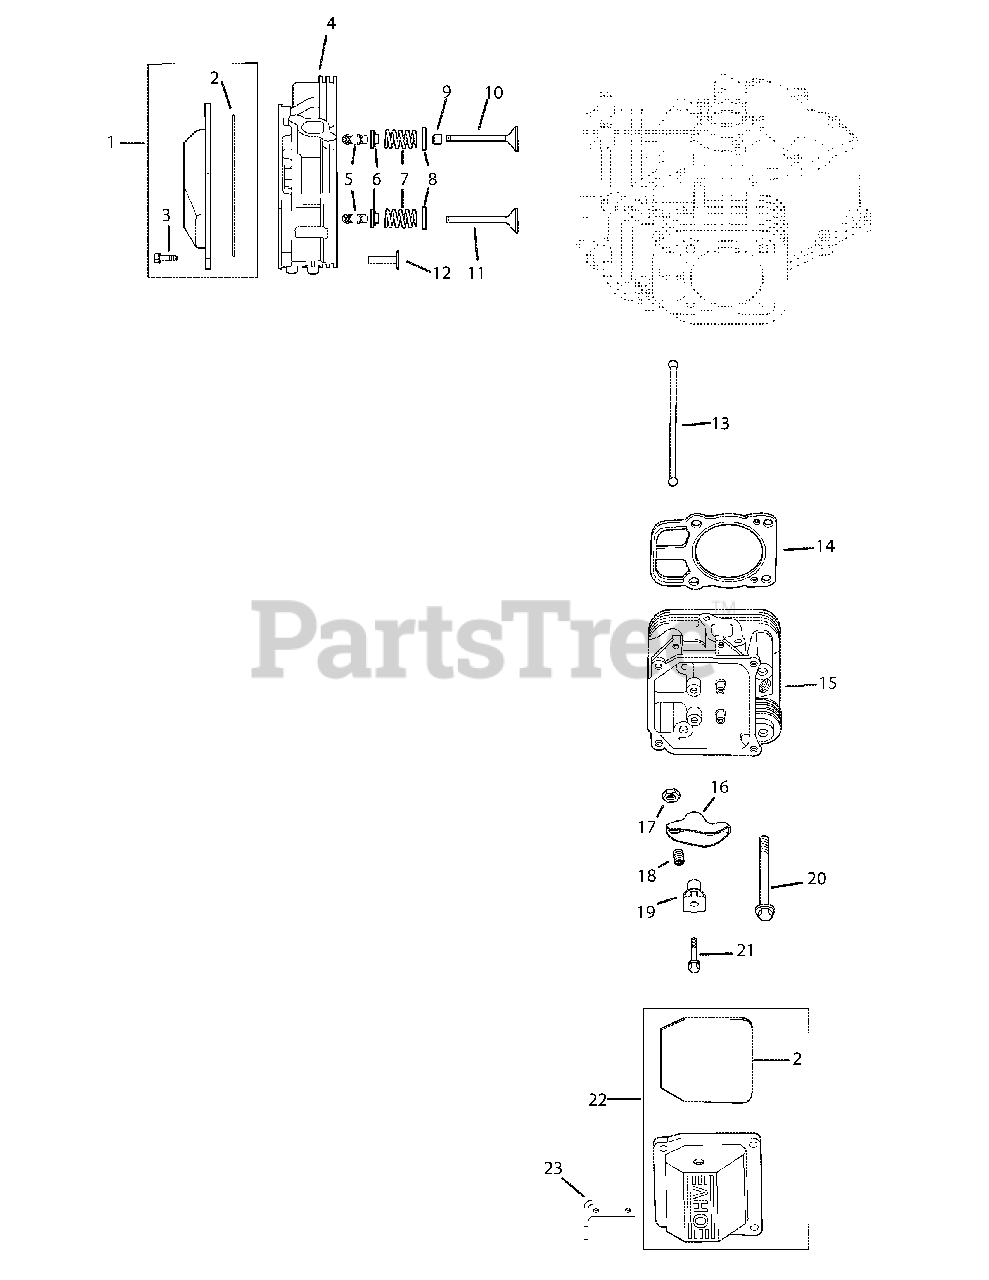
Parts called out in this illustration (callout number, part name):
1	Kit, valve cover - plain
3	Screw, hex. flange M6x1.0x30
4	Head assembly, #1 cylinder
5	Kit, retainer
6	Cap, valve spring
7	Spring, valve
8	Retainer, spring
9	Seal, valve stem
10	Valve, intake (Std.)
10	Valve, intake (.25)
11	Valve, exhaust (Std.)
11	Valve, exhaust (.25
12	Tappet
14	Kit, cylinder head gasket
15	Head assembly, #2 cylinder
16	Arm, rocker
17	Nut, hex. M10x0.75
18	Screw, set
19	Pivot, rocker arm
20	Screw,Hex. flange M10x1.5x90
21	Screw, hex. flange M6x1.0x45
22	Kit, valve cover - breather
23	Strap, lifting
